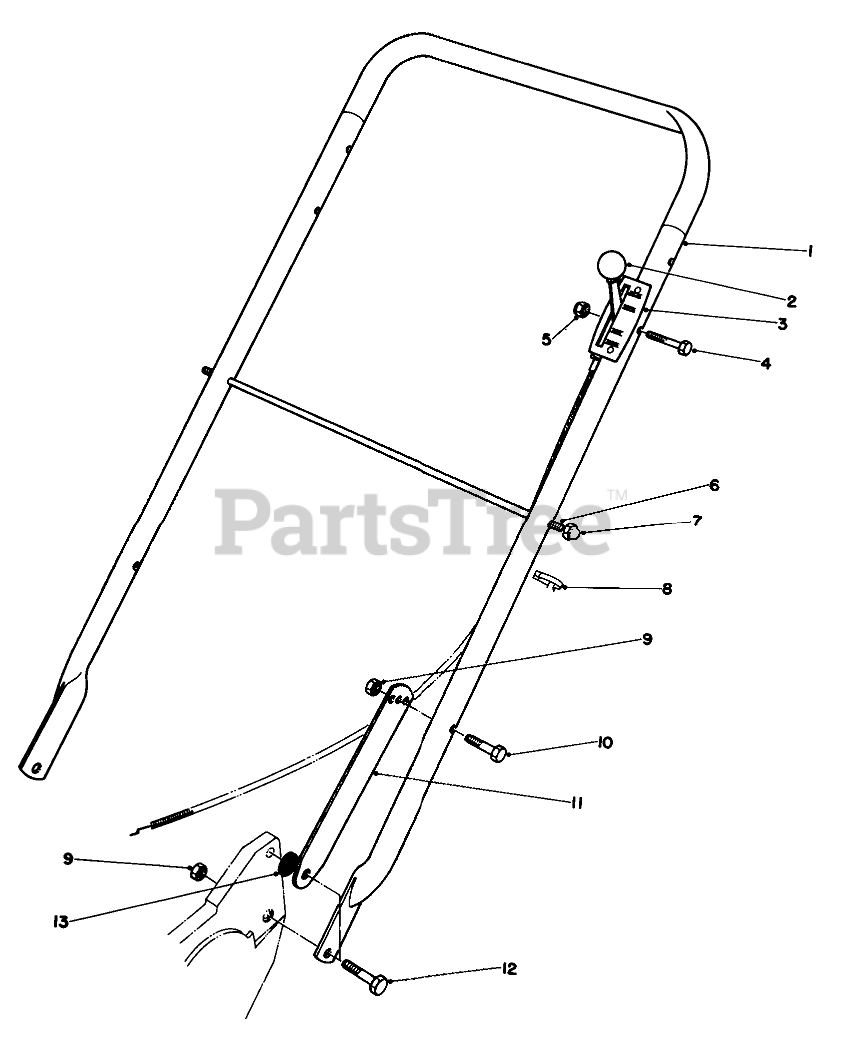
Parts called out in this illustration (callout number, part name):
1	Handle
2	KNOB-CONTROL
3	Control-Throttle (Incl. Ref. #2)
4	SCREW-HH
5	NUT-LOCK, NI
6	ROD-SUPPORT, BAG
7	NUT-CAP
9	NUT-LOCK, NI
10	SCREW-HH
11	Latch-Handle
12	SCREW-SHOULDER
13	HANDLE LATCH SPACER
